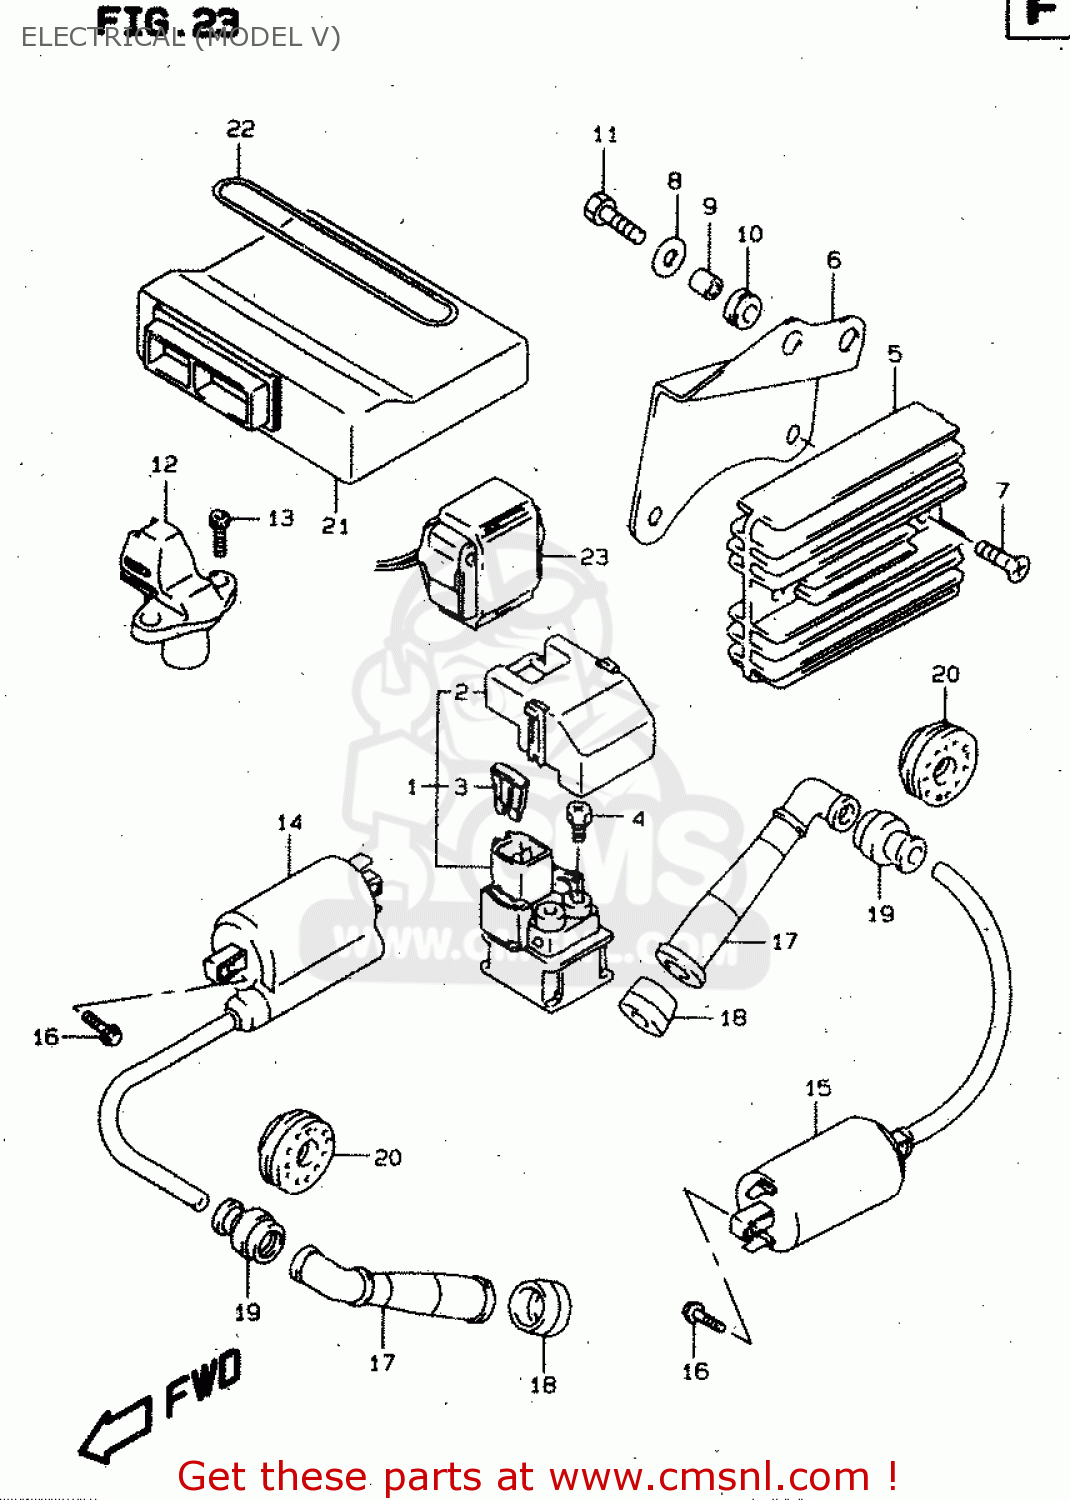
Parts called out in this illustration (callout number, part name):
1	RELAY ASSY,STARTING MOTOR
2	COVER,RELAY ASSEMBLY
3	FUSE(30A)
4	SCREW(6X8)
5	RECTIFIER ASSY
6	BRACKET,RECT FTG
7	SCREW (6X20)
8	WASHER(6.5X18X1.6)
9	SPACER(6.5X9X6.7)
10	CUSHION
11	BOLT
12	SENSOR ASSY,CAM POSITION
13	BOLT,OIL FILLE
14	COIL ASSY,IGNITION
15	COIL ASSY,IGNITION
16	SCREW, PRESSURE SENSOR
17	CAP,SPARK PLUG
18	SEAL,SPARK PLUG CAP
19	SEAL,HIGH TENSION CORD
20	COVER,SPARK PLUG CAP
21	CONTROL UNIT,EPI
22	BAND,BATTERY
23	SENSOR ASSY,FUEL CUT
